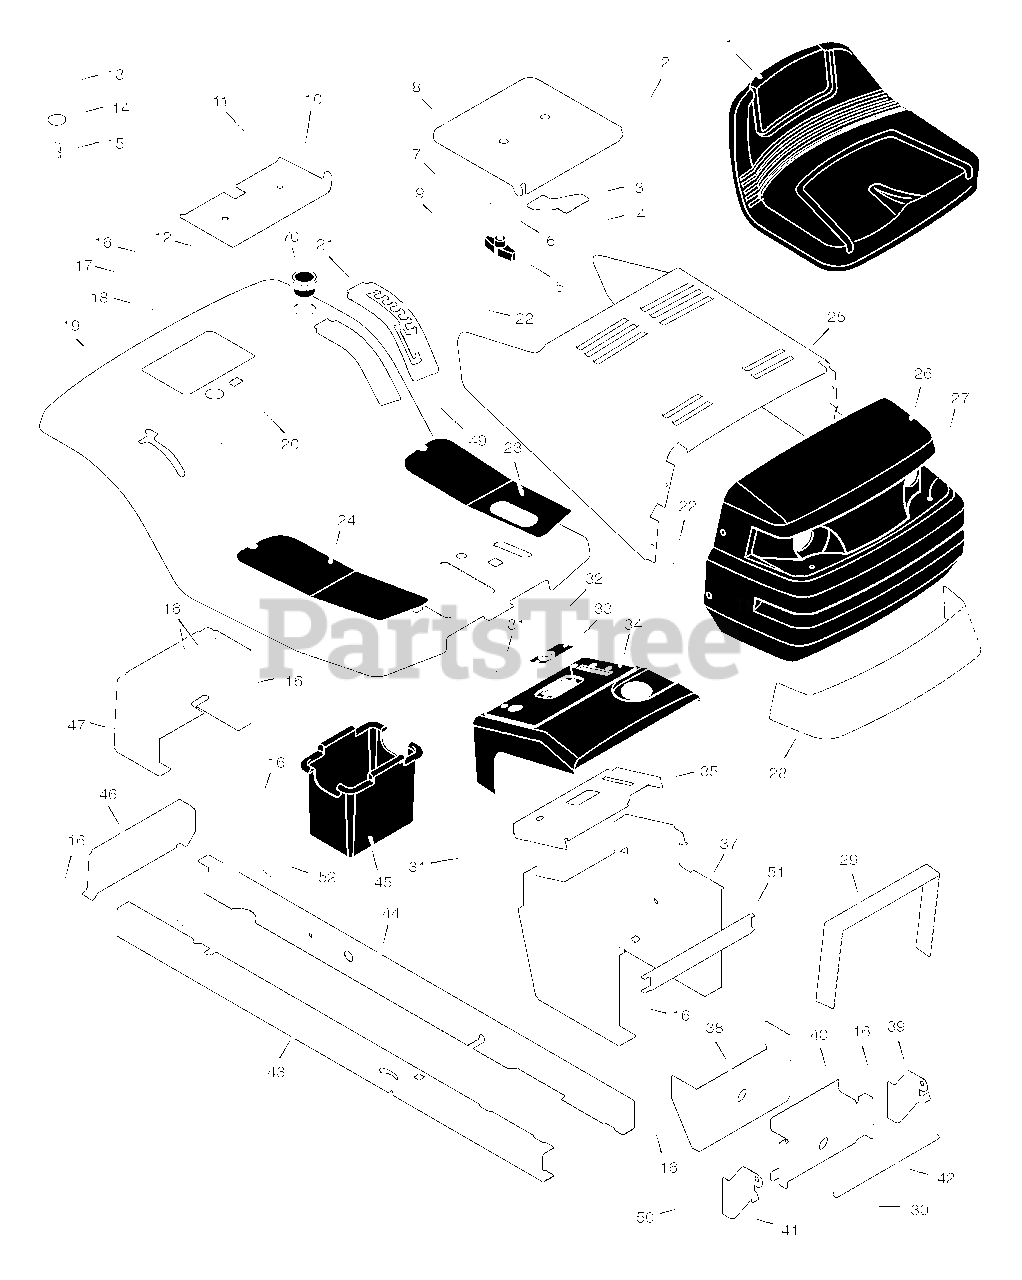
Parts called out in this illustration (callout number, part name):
1	Seat
2	Cap, Push On
5	Bolt, Wing
6	Washer
7	Bolt, Shoulder
8	Support, Seat
9	Rod, Pivot
10	Bracket, Pivot
11	Bolt
13	Bolt, Shoulder
15	Spring
19	Deck, Seat
20	Nut
21	Plate, Index
23	Mat, Left
24	Mat, Right
26	Grille Assembly
29	Brace, Grille
30	Pin, Hair
31	Screw
33	Bearing, Steering
35	Plate, Dash
36	Panel, Access
37	Support, Dash
38	Bracket, Rear Hanger
39	Support, Left Grille
40	Axle, Hanger
41	Support, Right Grille
42	Rod, Pivot
43	Frame, Right
44	Frame, Left
45	Container, Battery
46	Plate, Hitch
47	Panel, Rear
52	Support, Battery
70	Holder, Cup
